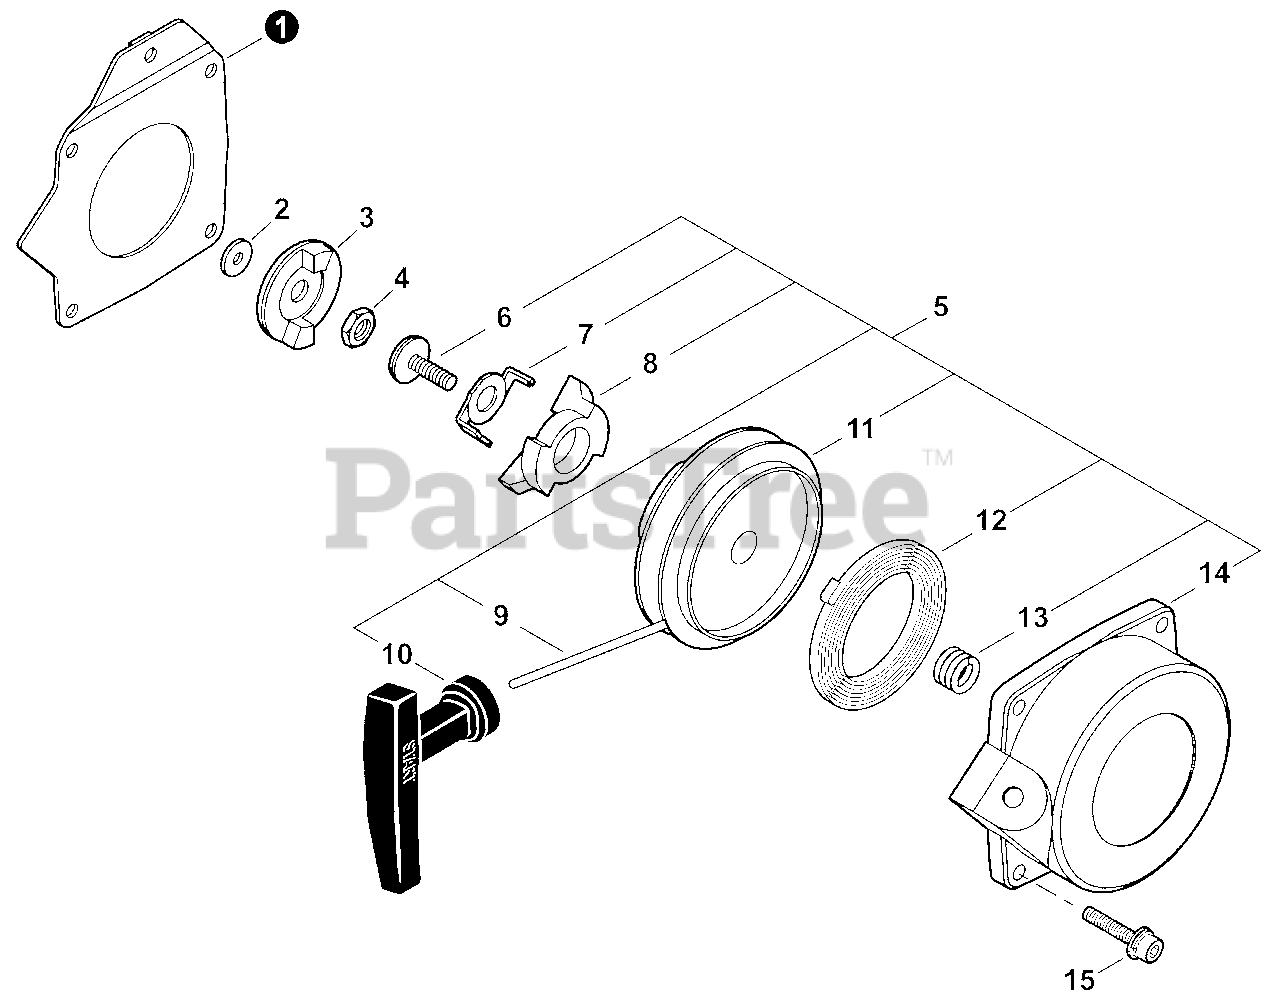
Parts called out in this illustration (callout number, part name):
1	PLATE, ANGLE
2	WASHER 8
3	PULLEY, STARTER
5	STARTER ASSY, RECOIL
7	RETAINER
8	PAWL, STARTER
9	ROPE, STARTER
10	GRIP, STARTER
11	REEL, ROPE
12	SPRING, RECOIL
13	SPRING, PAWL
14	CASE, RECOIL STARTER
15	BOLT M5×18
